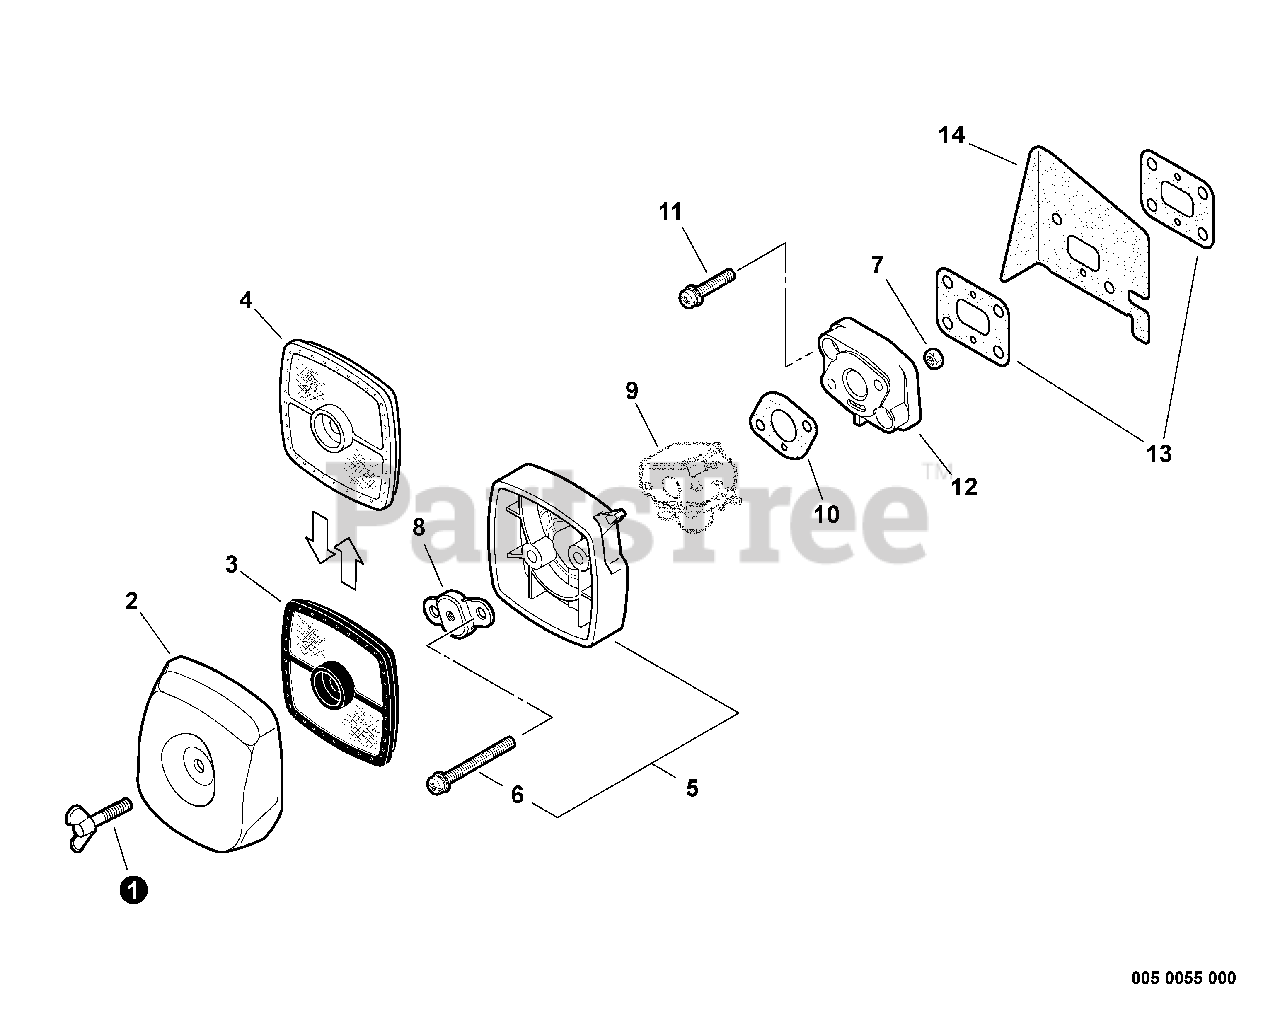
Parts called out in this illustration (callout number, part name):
1	THUMBSCREW
2	COVER, AIR FILTER - GRAY
3	FILTER, AIR - DOUBLE LAYER
4	FILTER, AIR - SINGLE LAYER
5	AIR FILTER CASE ASSY
6	SCREW - 5X65
8	PLATE, PREVENT
9	CARBURETOR
10	GASKET, INTAKE
11	SCREW - 5X22
12	INSULATOR, INTAKE
13	GASKET, INTAKE
14	SHIELD, INTAKE
